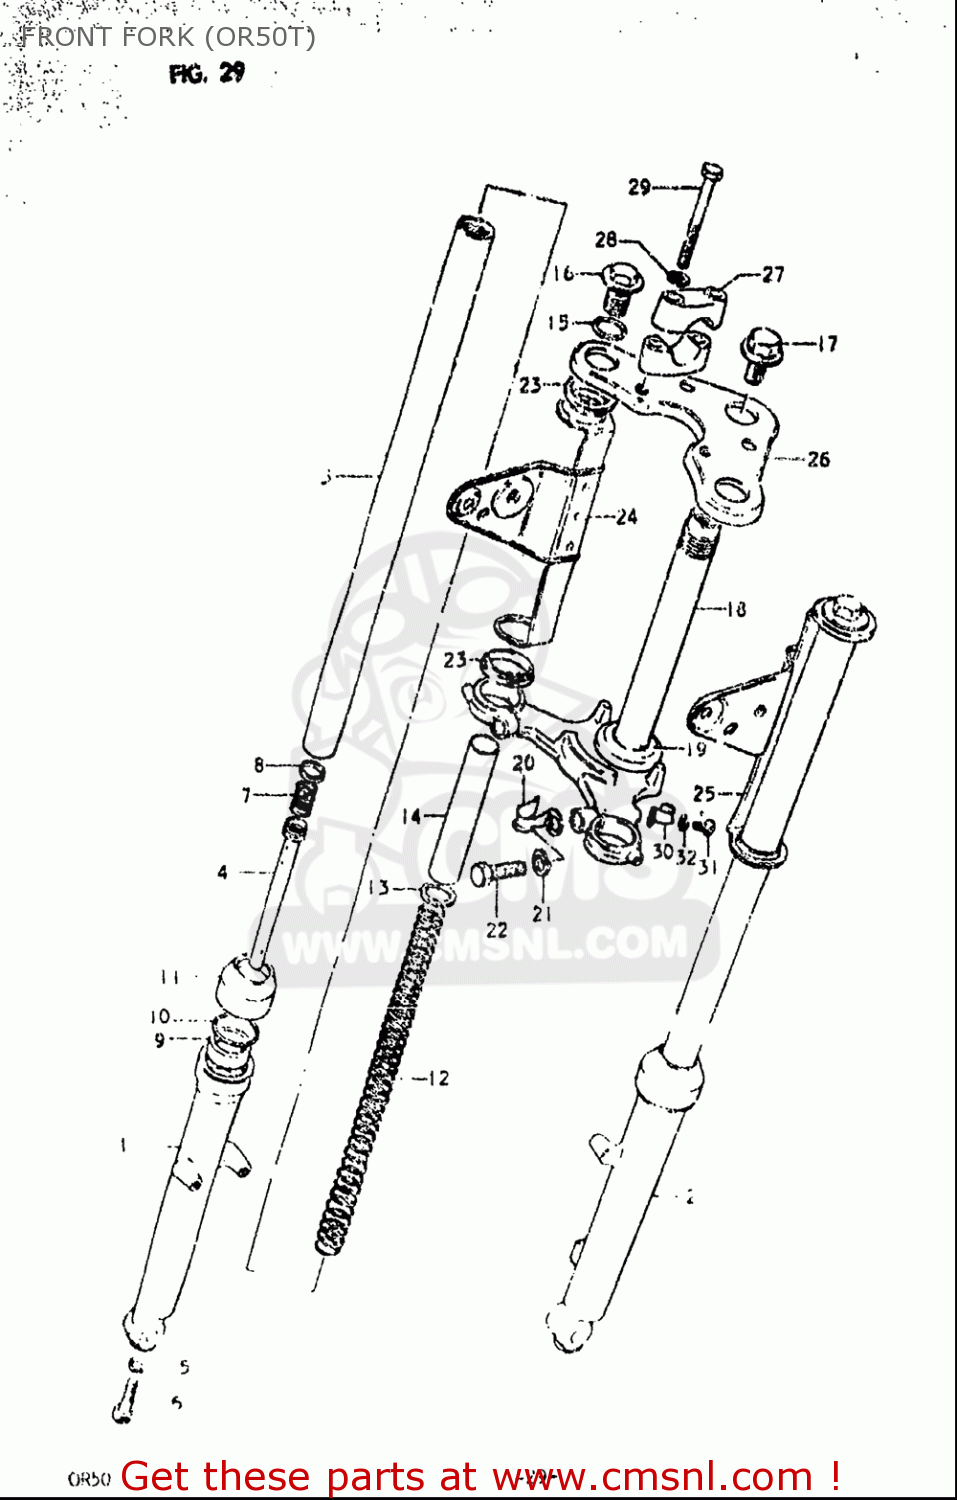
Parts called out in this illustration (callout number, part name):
5	GASKET (NAS)
6	BOLT(8X27)
7	SPRING,REBOUND
8	RING,PISTON
9	SEAL,OIL
10	RING,OIL SEAL STOPPER
11	DUST SEAL
12	SPRING,FRONT FORK
13	JOINT,SPRING
14	SPACER,SPRING
15	O RING(D:2.4,ID:17.8)
16	CAP
17	BOLT
19	RACE,STEERING OUTER LWR
20	CLIP,SPEEDOMETER CABLE
21	WASHER,LOCK
22	BOLT
23	CUSHION
27	HOLDER,HANDLE UPR
28	WASHER,LOCK
29	BOLT
30	CLIP
31	SCREW
32	WASHER,LOCK
